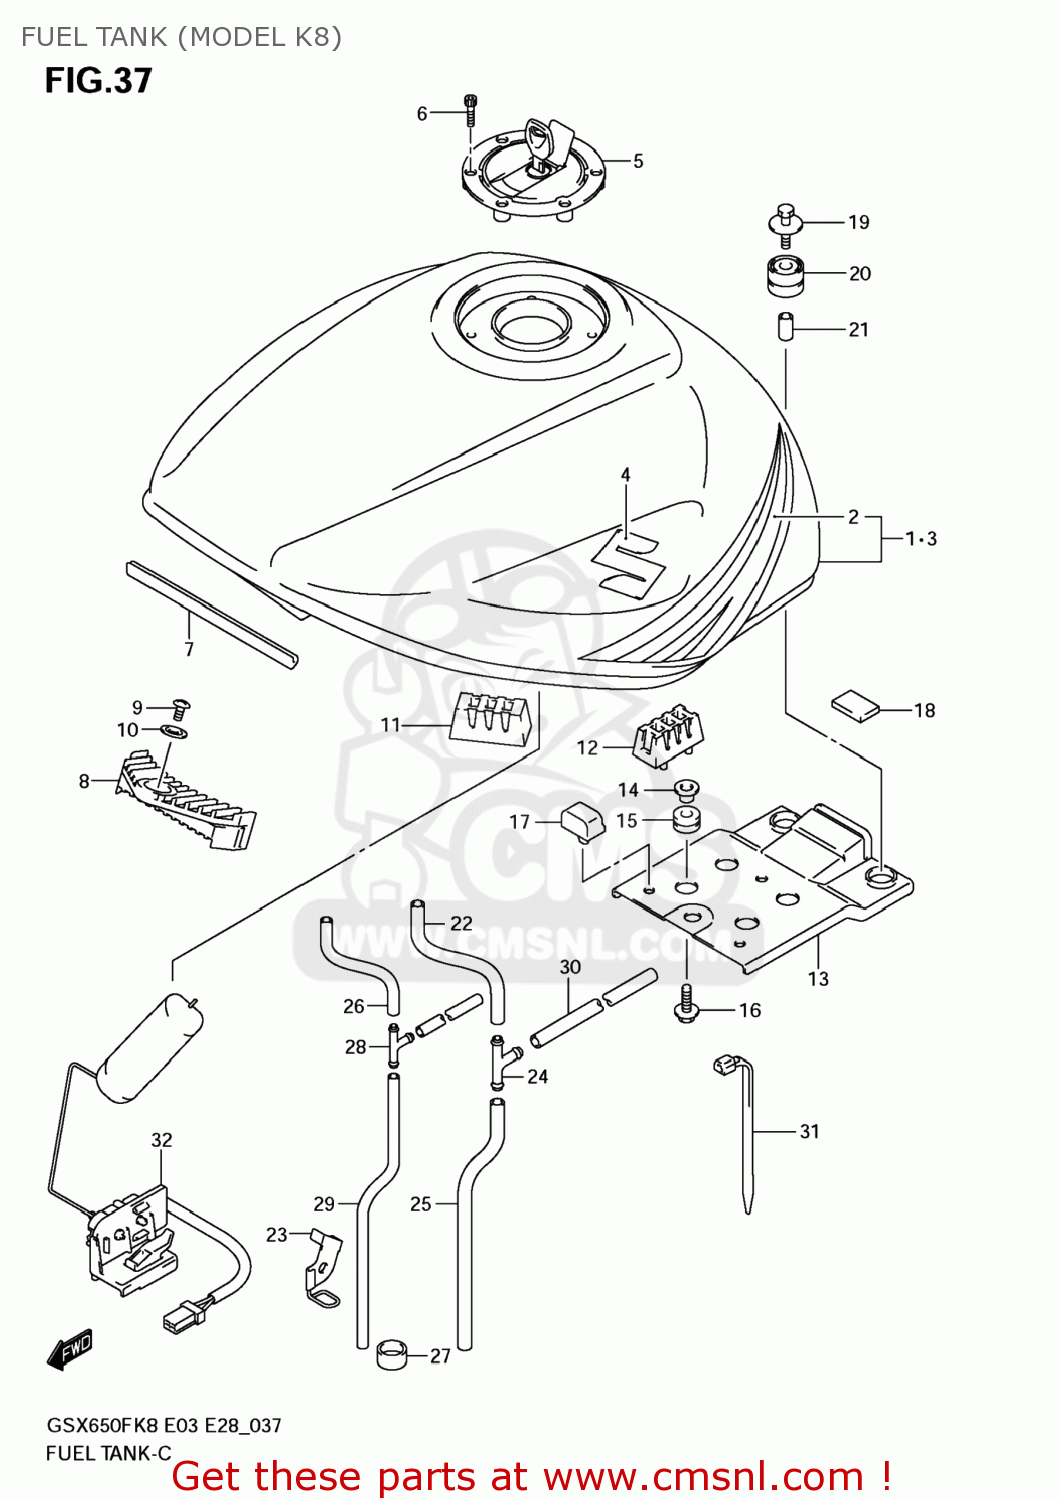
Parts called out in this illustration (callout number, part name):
1	TANK ASSY,FUEL(BLUE)
2	TAPE SET,FUEL TANK
3	TANK ASSY,FUEL(BLACK)
4	EMBLEM,S
5	CAP SET,FUEL TANK
6	BOLT(5X20)
7	MOLDING
8	CUSHION,FUEL TANK FR
9	SCREW
10	WASHER
11	CUSHION,SUPPORT(50X25X32)
12	CUSHION,TANK SIDE
13	BRACKET,FUEL TANK RR
14	WASHER
15	CUSHION
16	BOLT(6X20)
17	CUSHION
18	CUSHION,SIDE COVER BRACKET
19	BOLT(6X30)
20	CUSHION,FUEL TANK RR BRKT
21	SPACER(6.5X9X18)
22	HOSE,WATER DRAIN
23	GUIDE,DRAIN HOSE
24	3-WAY [FILTER TO PUMP)
25	HOSE(7X10.2X600)
26	HOSE,TANK BREA
27	HOSE(13.5X16.5X10)
28	JOINT,3 WAY
29	HOSE(5X8.2X600)
30	HOSE(5X8.2X2000)
31	CLAMP(L:125)
32	GAUGE ASSY,FUEL LEVEL SENDER
